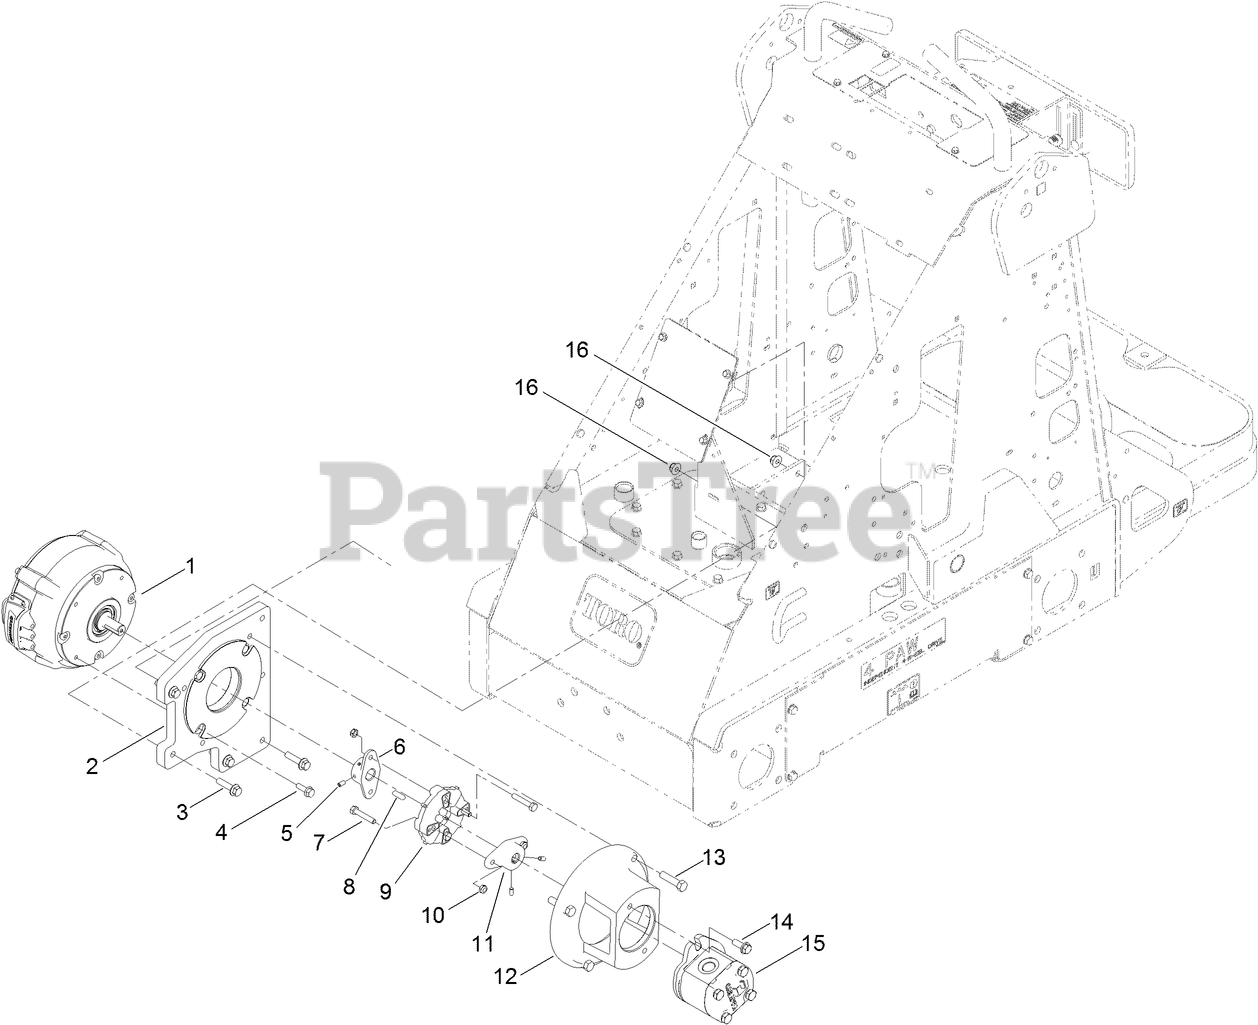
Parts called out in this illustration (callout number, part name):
1	MOTOR/GEN
2	PLATE-ADAPTER, MOTOR
3	SCREW-HHF
4	SCREW-HHF
5	SCREW-SET, HSH
6	HUB-PUMP
7	SCREW-HH
8	KEY-SQUARE
9	COUPLER-RUBBER
10	NUT-LOCK, NI
11	HUB-PUMP
12	MOUNT-PUMP
13	SCREW-HH
14	SCREW-HHF
15	PUMP-HYDRAULIC
16	NUT-HF, NI
